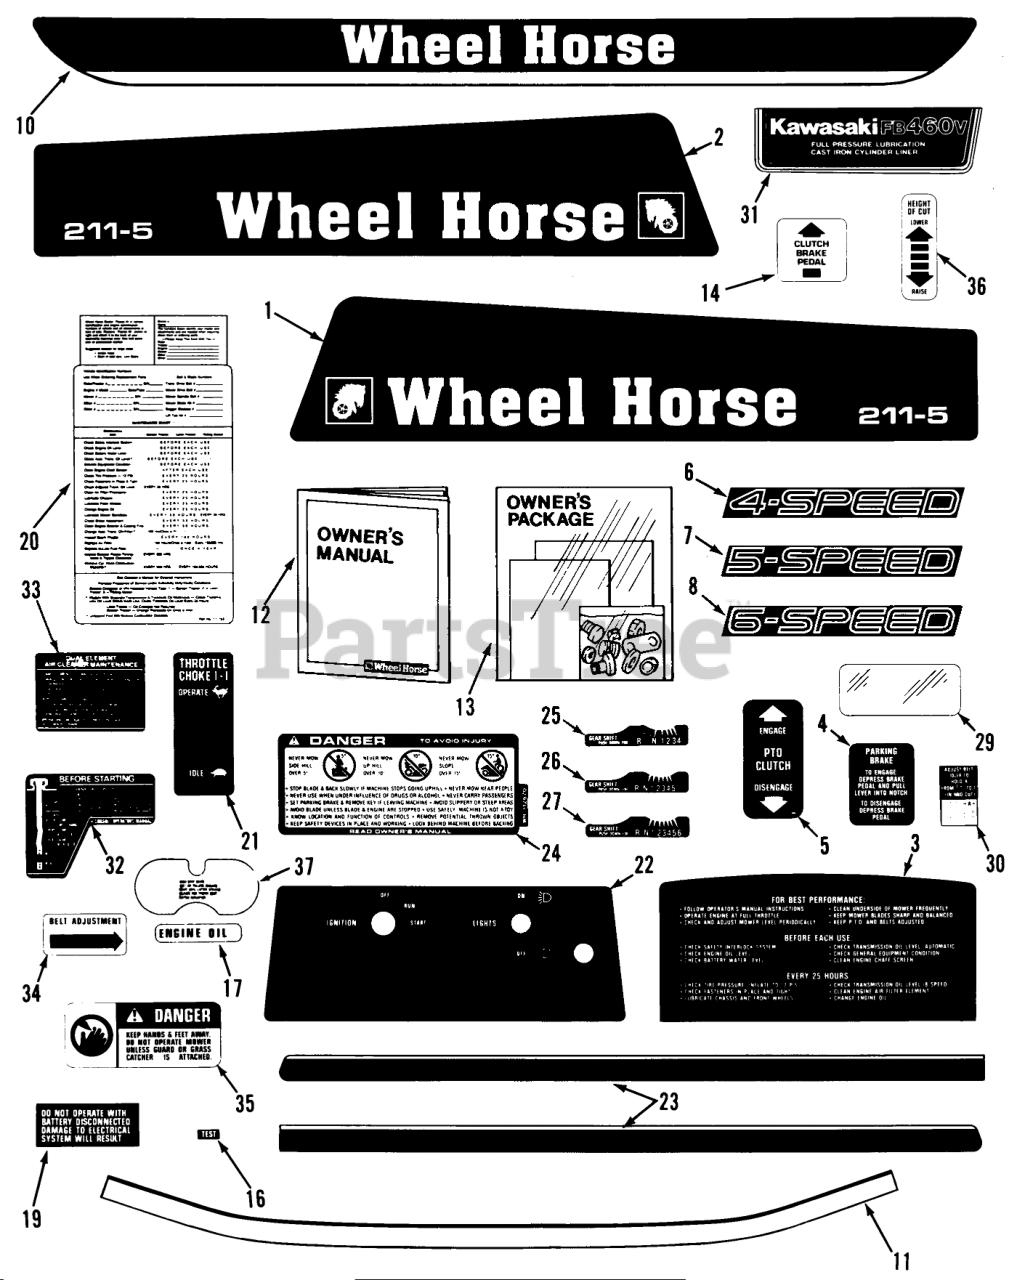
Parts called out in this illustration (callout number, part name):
1	Decal-Hood RH 208-4 Only
1	Decal-Hood RH 211-4 Only
1	Decal-Hood RH 211-5 Only
1	DECAL HOOD RH
2	Decal-Hood LH 208-4 Only
2	Decal-Hood LH 211-4 Only
2	Decal-Hood LH 211-5 Only
2	DECAL HOOD LH
3	DECAL REAR HOOD
4	DECAL PARKING BRAKE
5	DECAL-PTO
6	DECAL 4 SPEED
7	DECAL 5SPD
8	Decal-6-Speed
10	Decal-Rear Fender
11	DECAL FRONT HOOD
12	Owner-s Manual-Tractor
13	New Tractor Loose Parts Package 208-5 Only
13	New Tractor Loose Parts Package 211-4 Only
13	New Tractor Loose Parts Package 211-5 Only
13	New Tractor Loose Parts Package 212-6 Only
14	DECAL CLUTCH & BRAKE
16	Decal-Test 211-5 Only
17	Decal-Indicator Light 212-6
19	DECAL ELECT SYSTEM
20	Decal-Maintenance
21	DECAL-THROTTLE
22	DECAL-BACK PLATE
22	Decal-Back Plate 208-4
23	DECAL HOOD STRIPE RH
23	DECAL HOOD STRIPE LH
24	DECAL-DANGER
25	DECAL-SHIFT 4-SPEED
26	DECAL-SHIFT 5-SPEED
27	DECAL-SHIFT 6-SPEED
29	DECAL-OVERLAY
30	DECAL-PTO BELT ADJ
31	LABEL-BRAND
32	Decal-Engine Oil FB460V (vendor #56031-2249)
33	Decal-Air Cleaner Maint. (vendor #56031-2191)
34	DECAL-BELT ADJUST
35	Danger Decal
36	DECAL-HOC
37	DECAL-SEAT LIFTER
